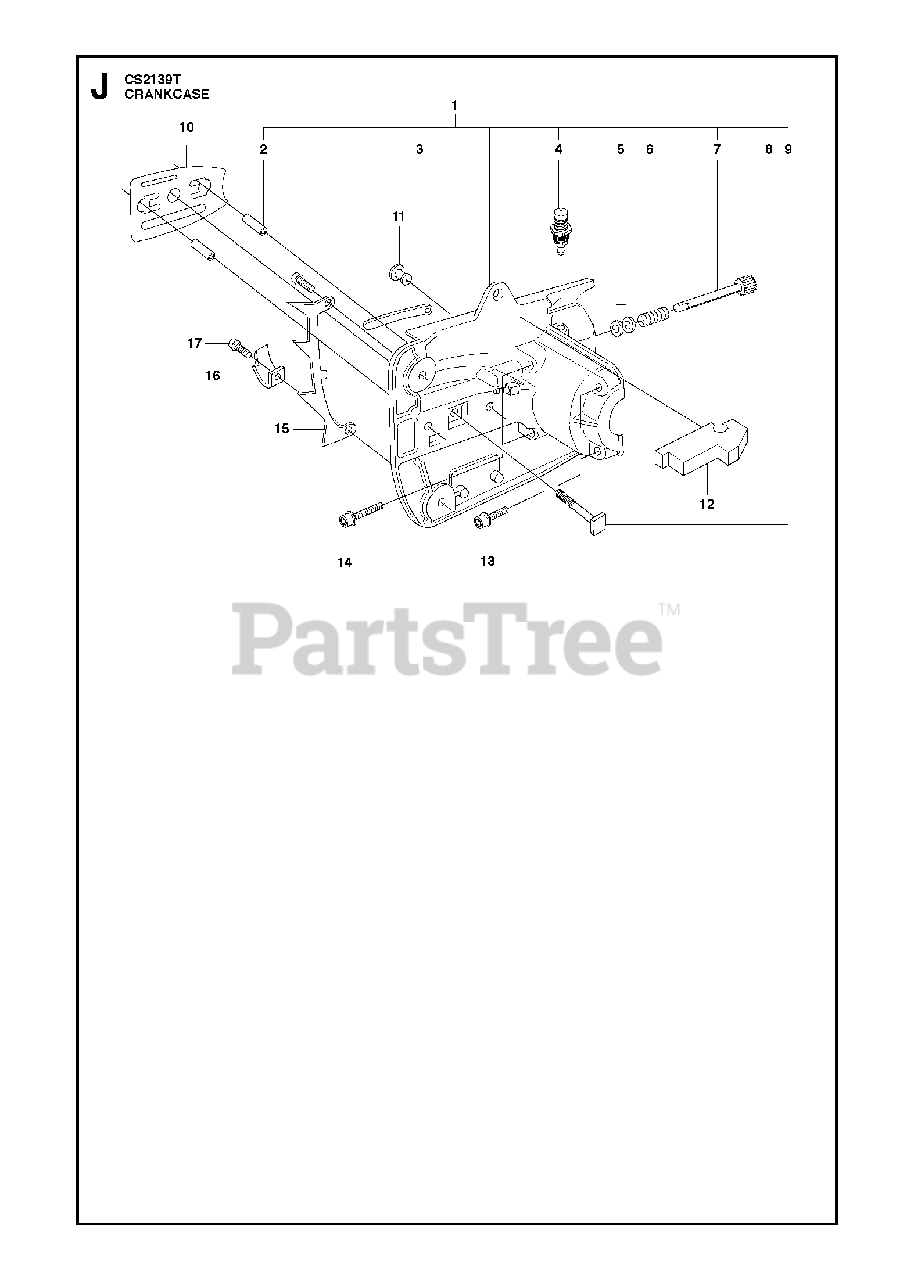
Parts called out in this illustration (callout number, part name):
1	CRANKCASE
2	GUIDE BAR LOCATING PIN
3	GASKET
4	INSERT OIL PUMP
5	WASHER 5.1X8.5
6	SPRING
7	PUMP PISTON
8	NIPPLE
10	CHAIN GUIDE PLATE
12	FOAM INSULATOR
15	FELLING DOG
16	CHAIN CATCHER
